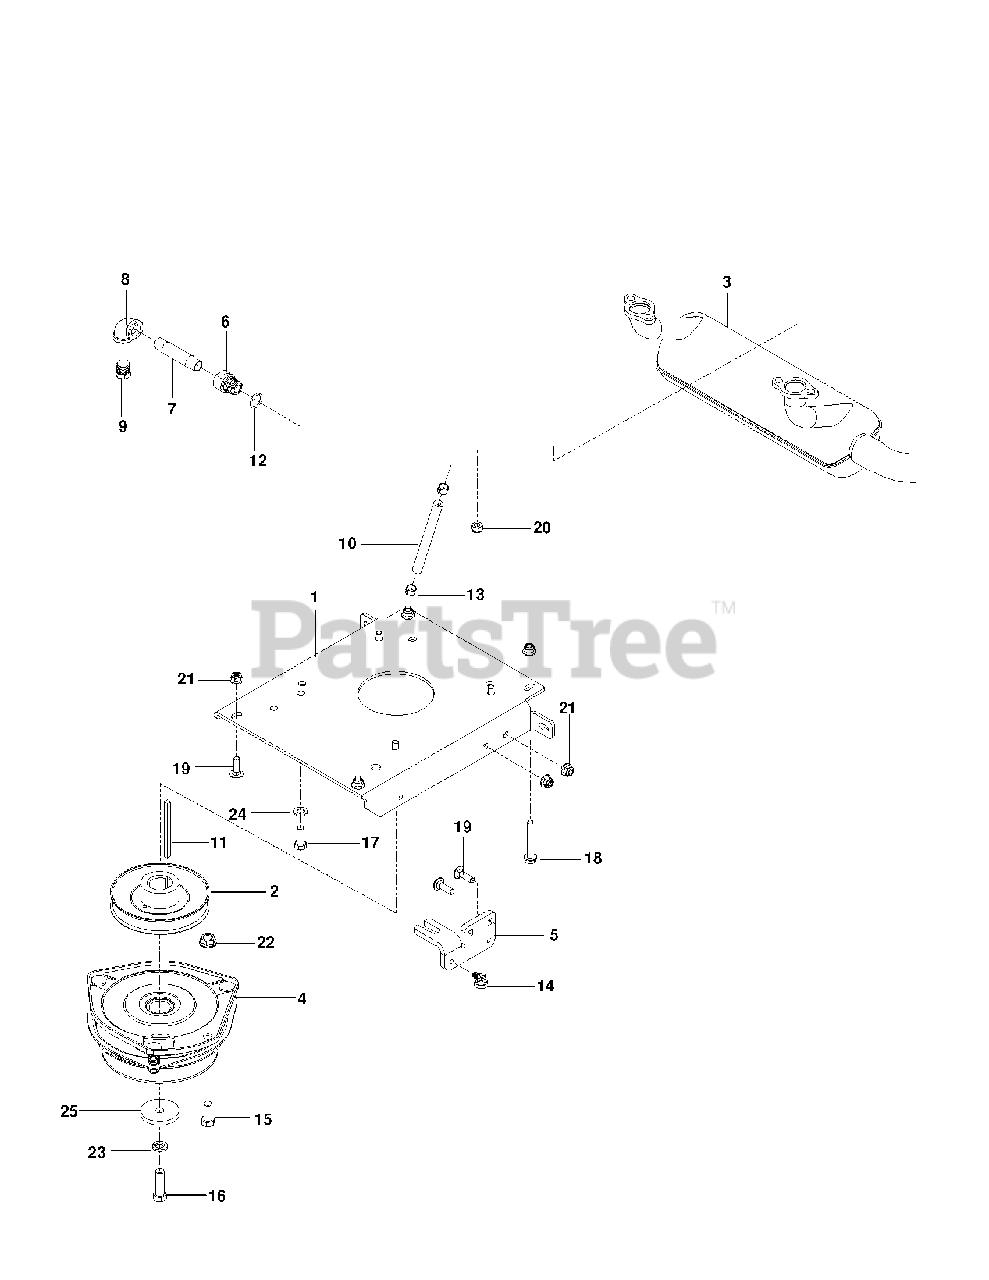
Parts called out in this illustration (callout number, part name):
1	PLATE, ENGINE, BLACK
2	PULLEY, ENGINE
3	MUFFLER, 29HP KAW FX751V-850V
4	CLUTCH, GT3.5
5	STOP, CLUTCH, OGURA
6	ADAPTER, OIL DRAIN
7	PIPE NIPPLE 3/8 X 3
8	90 DEG.ELBOW 3/8NPT
9	PLUG, DRAIN 3/8 NPTF
10	GAS LINE 10"
11	KEY, 1/4 SQ X 3.5
13	HOSE CLAMP
14	TIE WRAP, 8-3/8", W/CLIP
15	HCS 7/16-14 X 1 GR 5 ZD
16	HCS 7/16F X 1 1/2
17	HCS 3/8C X 1
18	HHFS 5/16-18 X 2.25 GD 5
19	RHSNB 5/16C X 1
20	NUT M8-1.25 TOP NYL GR10 ZD
21	5/16-18 NYLOC FLANGE NUT
22	NUT 7/16C WHIZ
23	WASHER 7/16 LOCK
24	WASHER, 3/8 DISC SPRING SPEC
25	BLADE WASHER
